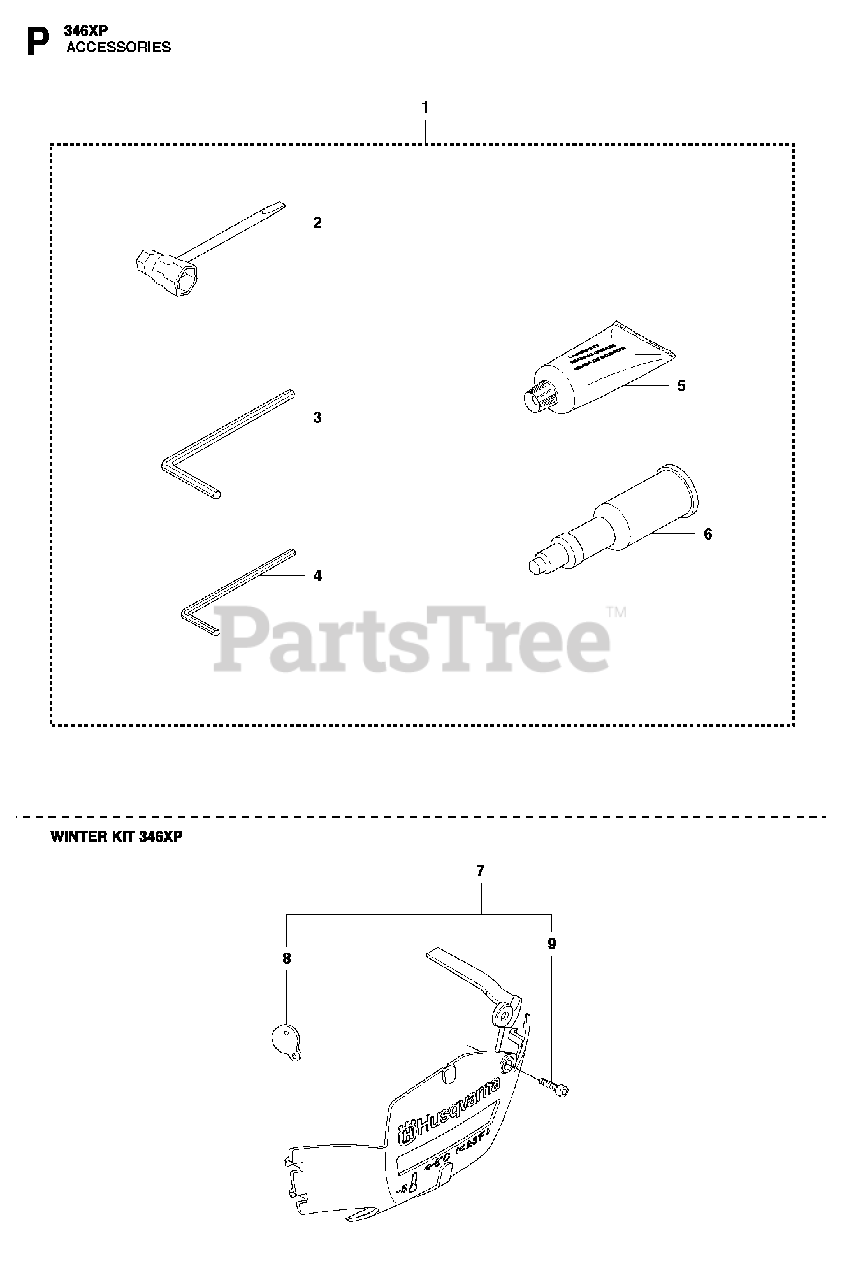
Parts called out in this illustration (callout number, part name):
1	TOOL KIT
2	COMBI TOOL
3	L-SPANNER
4	L-SPANNER
5	GREASE
6	Grease Gun
7	WINTER COVER
8	COVER
9	SCREW
